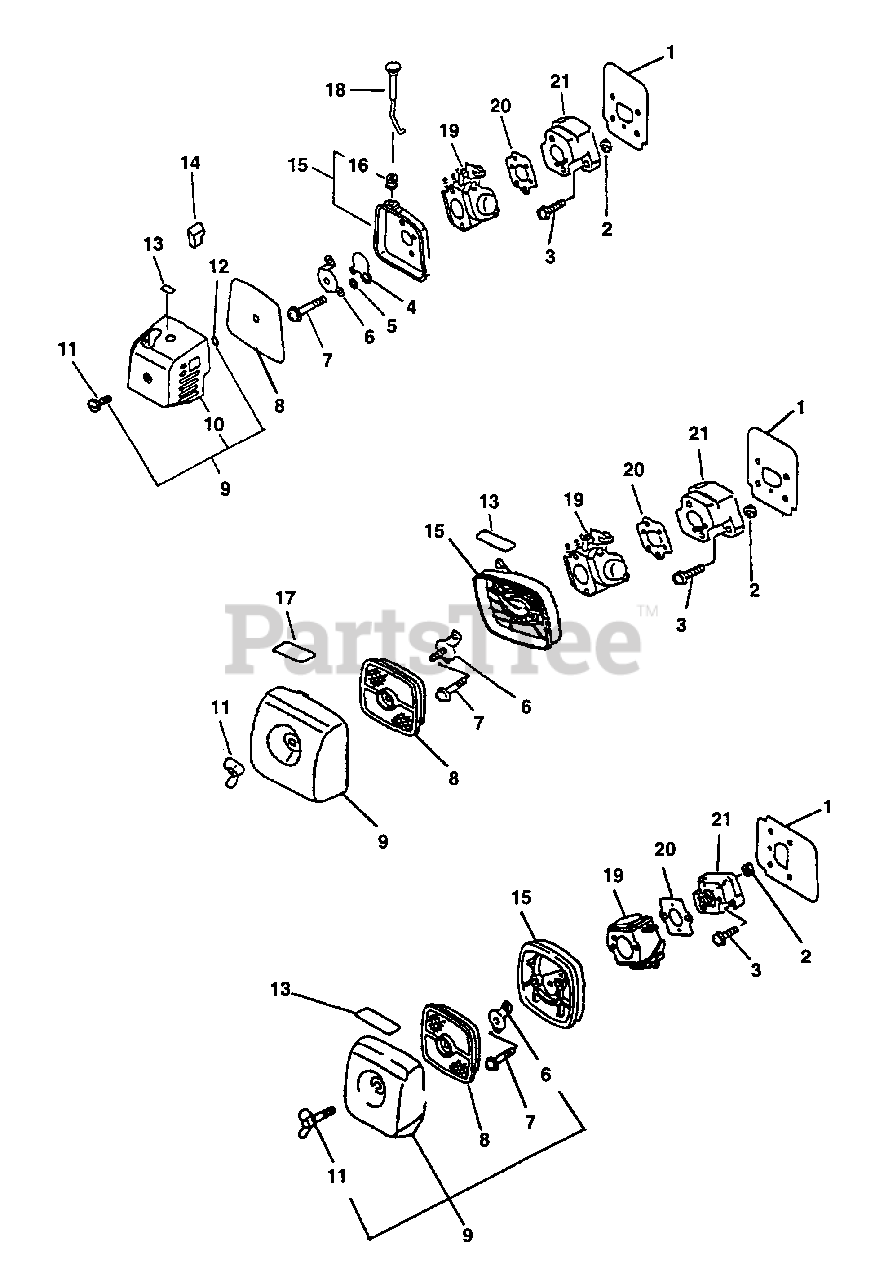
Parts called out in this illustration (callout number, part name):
1	SHIELD, INTAKE
3	SCREW - 5X20
4	SHUTTER, CHOKE
5	WASHER - 5
6	BRACKET, AIR CLEANER
6	PLATE, PREVENT
7	SCREW - 5X57
7	SCREW - 5X65
8	FILTER, AIR
8	FILTER, AIR - SINGLE LAYER
9	AIR FILTER COVER ASSY
9	COVER, AIR FILTER
9	COVER, AIR FILTER - GRAY
10	COVER, AIR FILTER
11	SCREW
11	WINGNUT - 6
11	THUMBSCREW
12	O-RING - 4
13	LABEL - CHOKE
15	CASE, AIR FILTER
15	AIR FILTER CASE ASSY
17	LABEL - TOP
18	ROD, CHOKE
19	CARBURETOR C1U-K23A
19	CARBURETOR WT-424A
20	GASKET, INTAKE
21	INSULATOR, INTAKE
